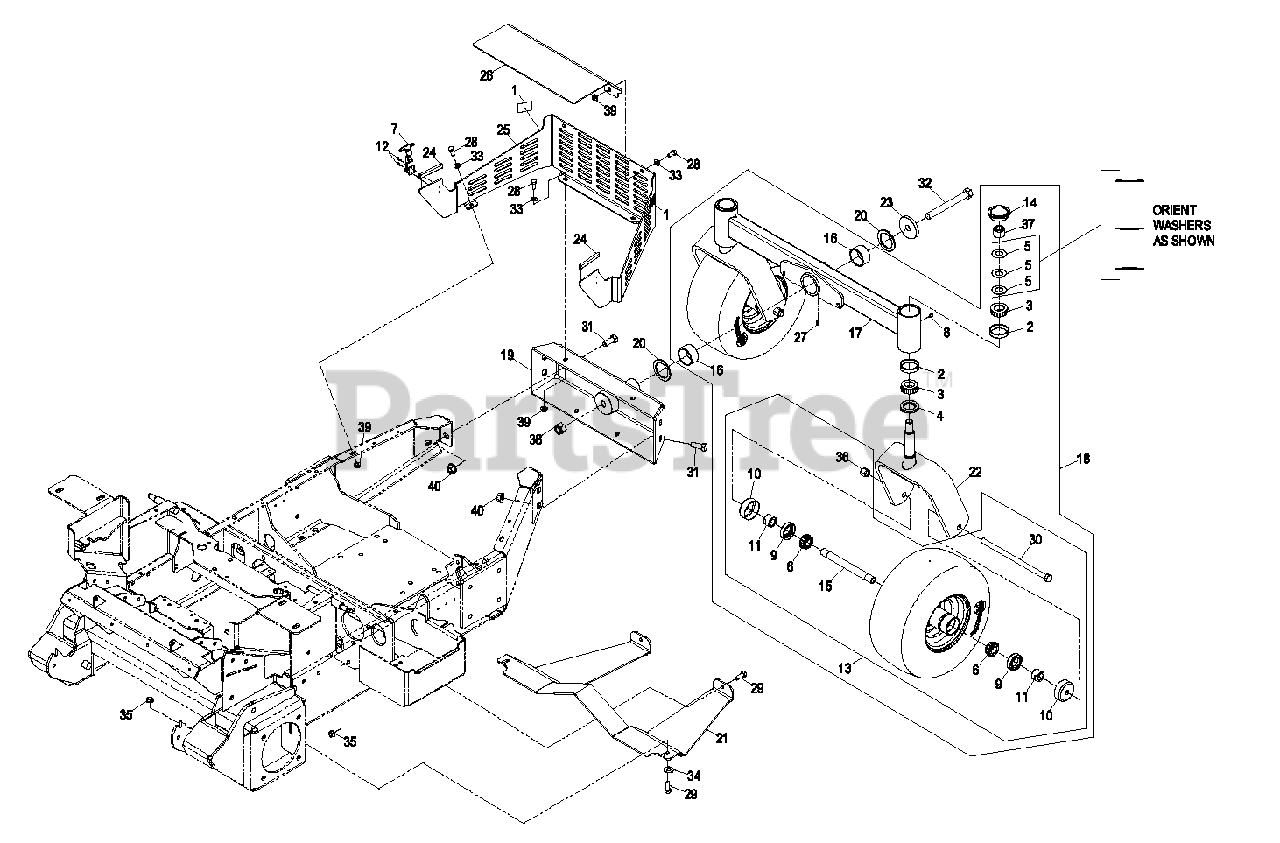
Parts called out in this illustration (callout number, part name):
2	CUP-BEARING
3	Cone-Bearing Tapered Roller
4	SEAL-GREASE
5	WASHER-BELLVILLE
6	BEARING-CONE, TAPERED ROLLER
7	LATCH-RUBBER
9	SEAL-CASTER
10	GUARD-SEAL
11	SPACER-NUT
14	CAP-GREASE
16	BEARING,1.75"ID X 2"OD
18	Asm, Dual Rear Wheels
20	BEARING,THRUST
23	WASHER (PLATED)
24	STRIP-SEAL
25	ASM,FMZ REAR GUARD
26	COVER,MUFFLER FMZ
26	COVER,MUFFLER
27	FITTING-GREASE
28	SCREW-HH
29	SCREW-HH
30	SCREW-HH
31	SCREW-HH
32	SCREW-HH
33	WASHER-PLAIN
34	WASHER-FLAT
35	NUT-HHF, WHIZ
36	NUT-LOCK, NI
37	NUT-LOCK, NI
38	NUT-LOCK, NI
40	NUT-HHF
